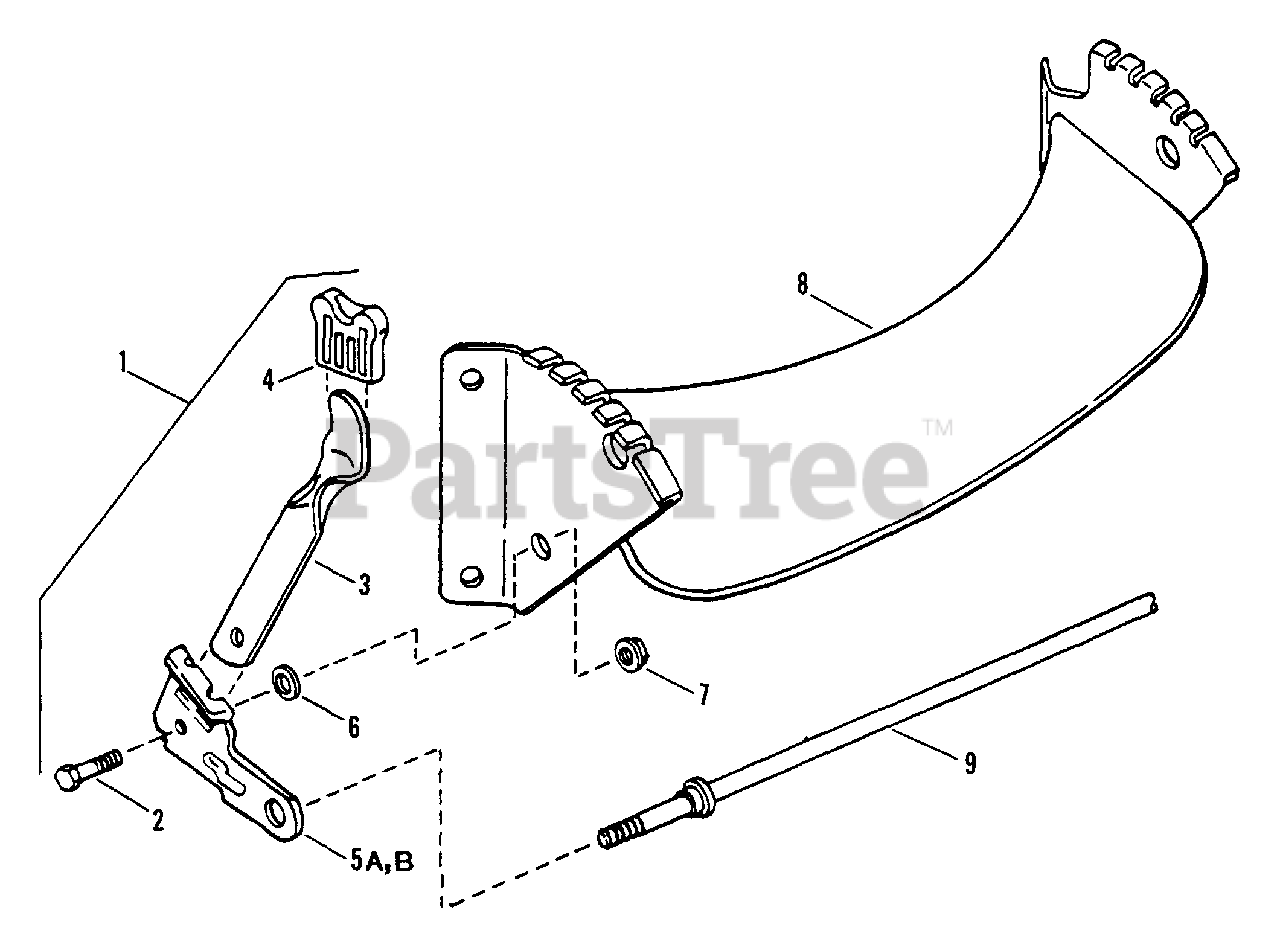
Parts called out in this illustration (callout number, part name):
1	ASSEMBLY, Arm, Left Wheel
2	BOLT, 5/16-18 x 3/4" Shoulder
3	LATCH, Height
4	GRIP, Latch
5A	ARM, Left Wheel
5B	ARM, Right Wheel
6	RETAINER, 5/16 Bolt
7	NUT, 5/16-18 Hex Flange
8	BRACKET, Front Wheel
9	AXLE
